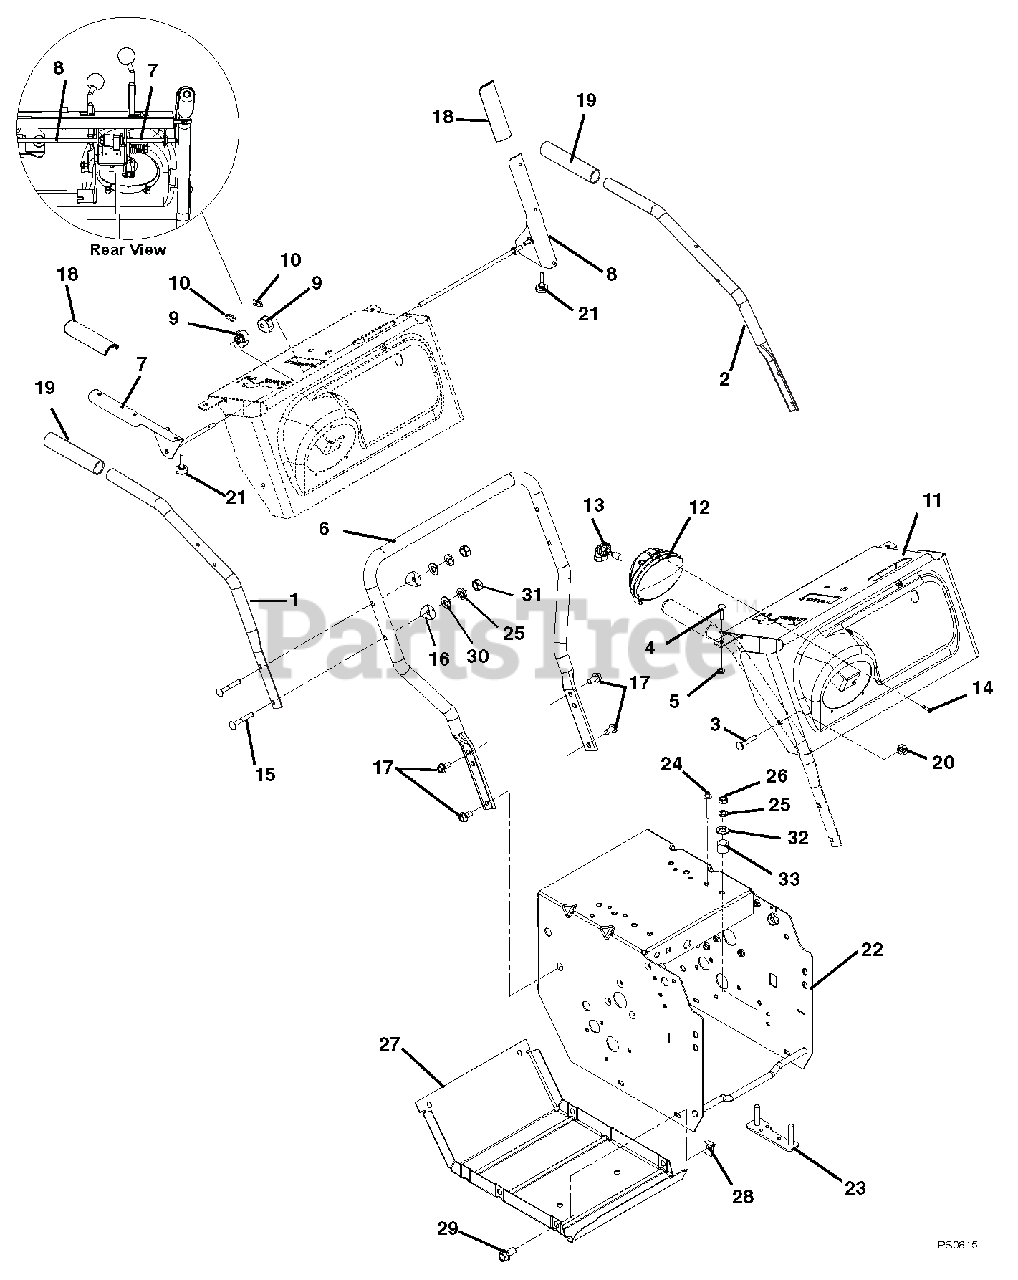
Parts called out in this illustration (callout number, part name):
1	HANDLEBAR, UPPER-RH
1	HANDLEBAR, UPPER RH-W/HW
2	HANDLEBAR, UPPER-LH
2	HANDLEBAR, UPPER LH-W/HW
3	@BLT-RDHDSQNK .31-18X1.75 G5YZ
4	BLT-RDHDXLSQNK.25-20X1.25 G5ZC
5	@NUT-LK-TOP-FLG .25-20 YWZC
6	HANDLEBAR, LOWER - DELUXE
7	LEVER, RH-ATTACHMENT
8	LEVER, LH-TRACTION
9	CAM, INTERLOCK NYLON, LG DASH
10	PIN, SPRING CLIP
11	CONTROL PANEL W/DECAL
11	DASH PANEL W/CONTROL DECAL
12	LIGHT, HALOGEN ASSY.
12	LIGHT, HALOGEN ASSY 12W
13	BULB, LIGHT-HALOGEN 20W
13	BULB, LIGHT, HALOGEN - 12W
14	SCR-TAP 10-16X.75 HI-LO PPH
15	@BLT-RDHDSQNK .31-18X2.25 G5YZ
16	SPACER, HANDLEBAR
17	BLT-SERHFWH .38-16X.75 YWZC
18	GRIP, CLUTCH LEVER, LH AND RH
19	HANDLE GRIP
20	@NUT-LK-CTR .31-18 YWZC
21	BUMPER, RUBBER - PULL MOUNT
22	FRAME, 920/921
23	STRAP, ENGINE BOLT-WELDMENT
23	STRAP, ENGINE BOLT-LARGE BRIGG
24	RVT-POP .187 YZ
25	WSHR-LK .312X.097 HVY YWZC
26	@NUT-HEX .31-18 YWZC
27	COVER, BOTTOM
28	NUT-RTNR .25-20X.56
29	BLT-HEX .25-20X.75 HWH YZ GR5
30	@WSHR-FL-STL.38X.875X.083 YWZC
31	@NUT-LK-NYL .312-18 YWZC
32	@WSHR-FL-STL.344X.688X.065YWZC
33	BSHG-SLV .325X.400X.795
